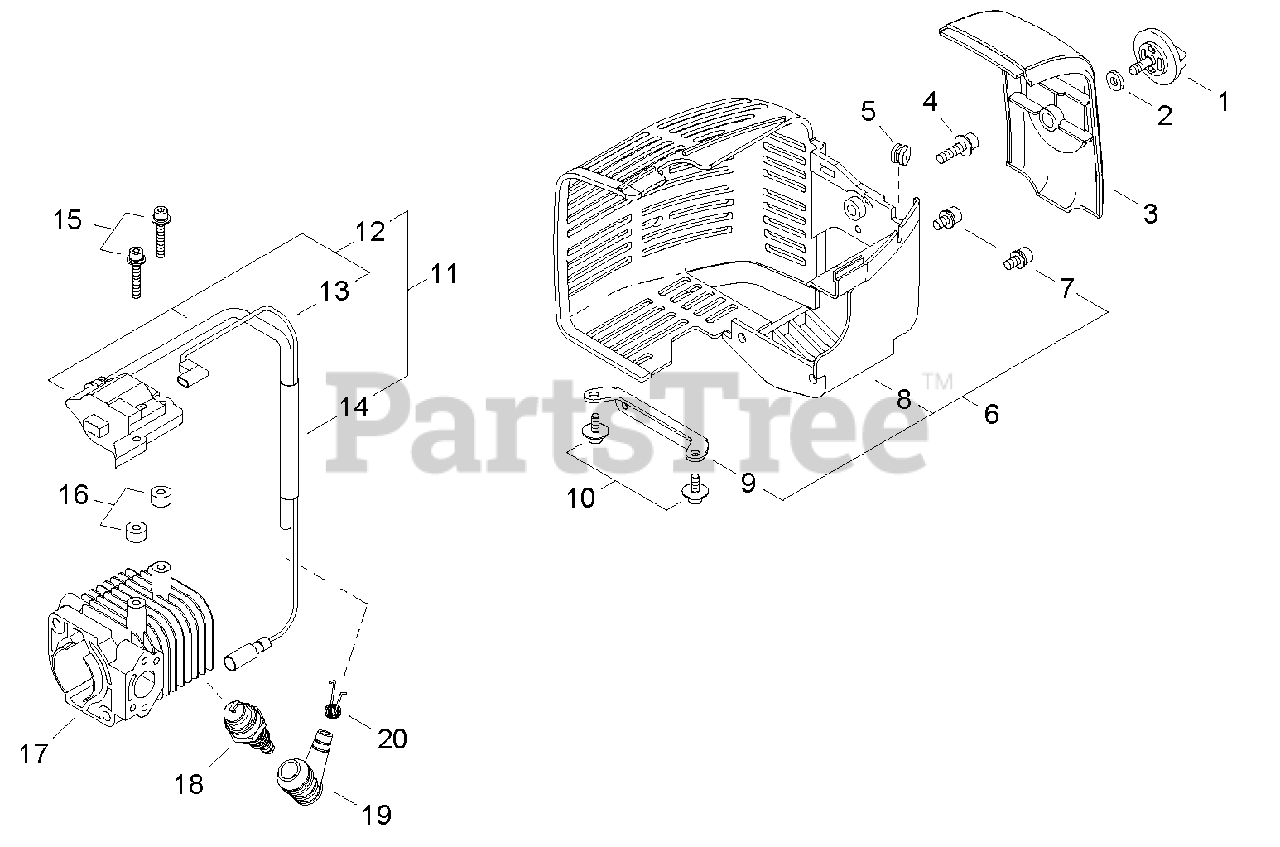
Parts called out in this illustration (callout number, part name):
1	THUMBSCREW
2	WASHER 5
3	COVER, SPARK PLUG
4	BOLT, ADHESIVE M5×20
5	GROMMET, LEAD
6	COVER ASSY, ENGINE
7	BOLT, ADHESIVE 5
8	COVER, ENGINE
9	STAY, ENGINE COVER
10	BOLT, ADHESIVE 4
11	COIL KIT, IGNITION
12	COIL ASSY, IGNITION
13	LEAD - IGNITION
14	TUBE, IGNITION COIL
15	BOLT M4×26
16	INSULATOR 4.2×11×6
17	CYLINDER
18	SPARK PLUG - BPMR6A
19	CAP, SPARK PLUG
20	TERMINAL, SPARK PLUG
